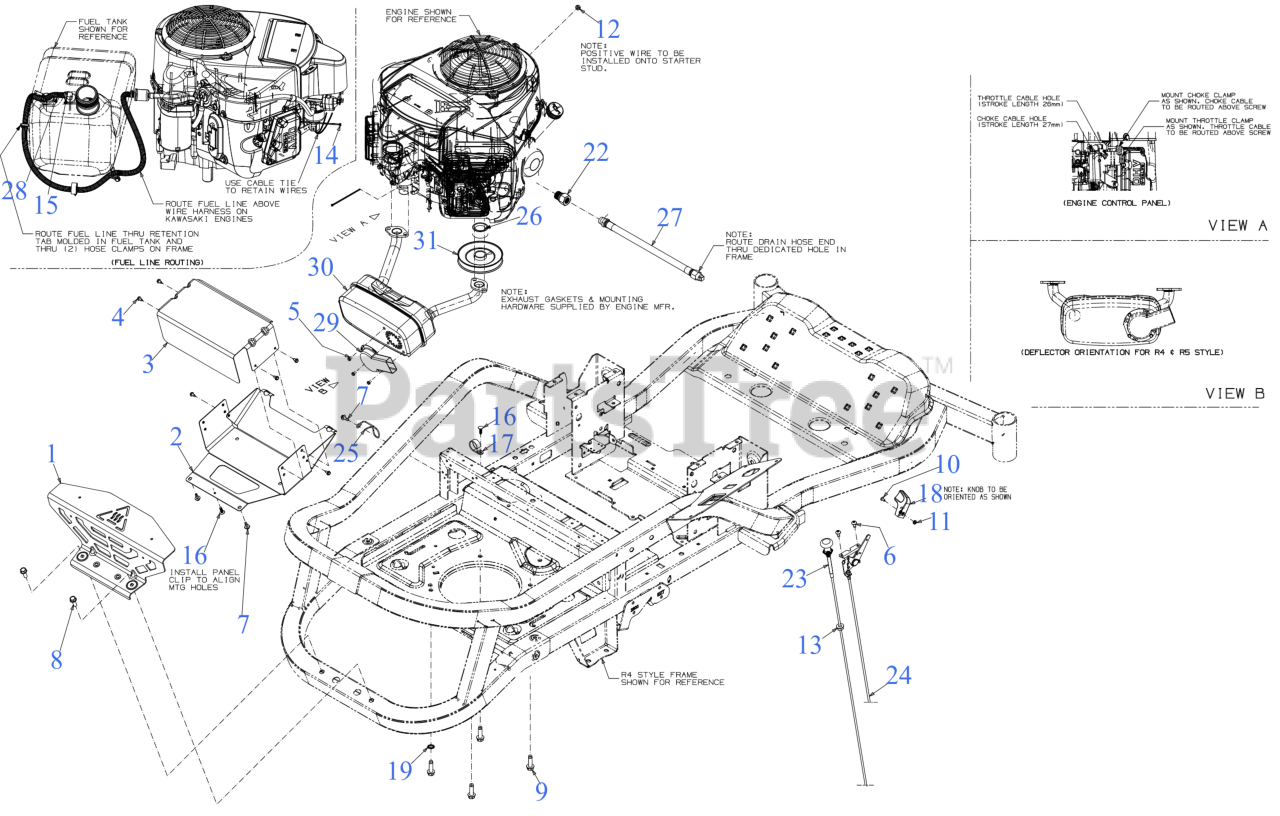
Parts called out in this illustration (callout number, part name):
1	MUFFLER COVER (REAR) (BLACK)
2	MUFFLER SHIELD (LOWER)
3	MUFFLER SHIELD (TOP)
4	HEX SCREW AB-TAP #10 x .50
5	HEX SCREW WASHER HD #8-18 x 0.500
6	SCREW 1/4-20 x .5
7	SCREW M6-1 x .625
8	SCREW 5/16-18 x .875 GR5
9	SCREW 3/8-16 X1.250
10	SCREW #8-32X.38 LG
11	HEX NUT 8-32
12	HEX NUT 1/4-20
13	HEX FLANGE NUT
14	CABLE TIE
15	HOSE CLAMP 1/20
16	RATCHET CLIP (.188 x .85)
17	DRAIN HOSE CLAMP
18	THROTTLE CONTROL KNOB
19	LOCK WASHER 3/8
22	OIL DRAIN FITTING (M20x2.5)
23	CHOKE CABLE 40.5 LG
24	THROTTLE CABLE 38.5"
25	HOSE GUIDE
26	ENGINE PULLEY SPACER
27	OIL DRAIN HOSE
28	FUEL HOSE LOW PERMEATION 28"
29	EXHAUST DELECTOR (LONG)
30	EXHAUST MUFFLER
31	TRANSMISSION DRIVE PULLEY
